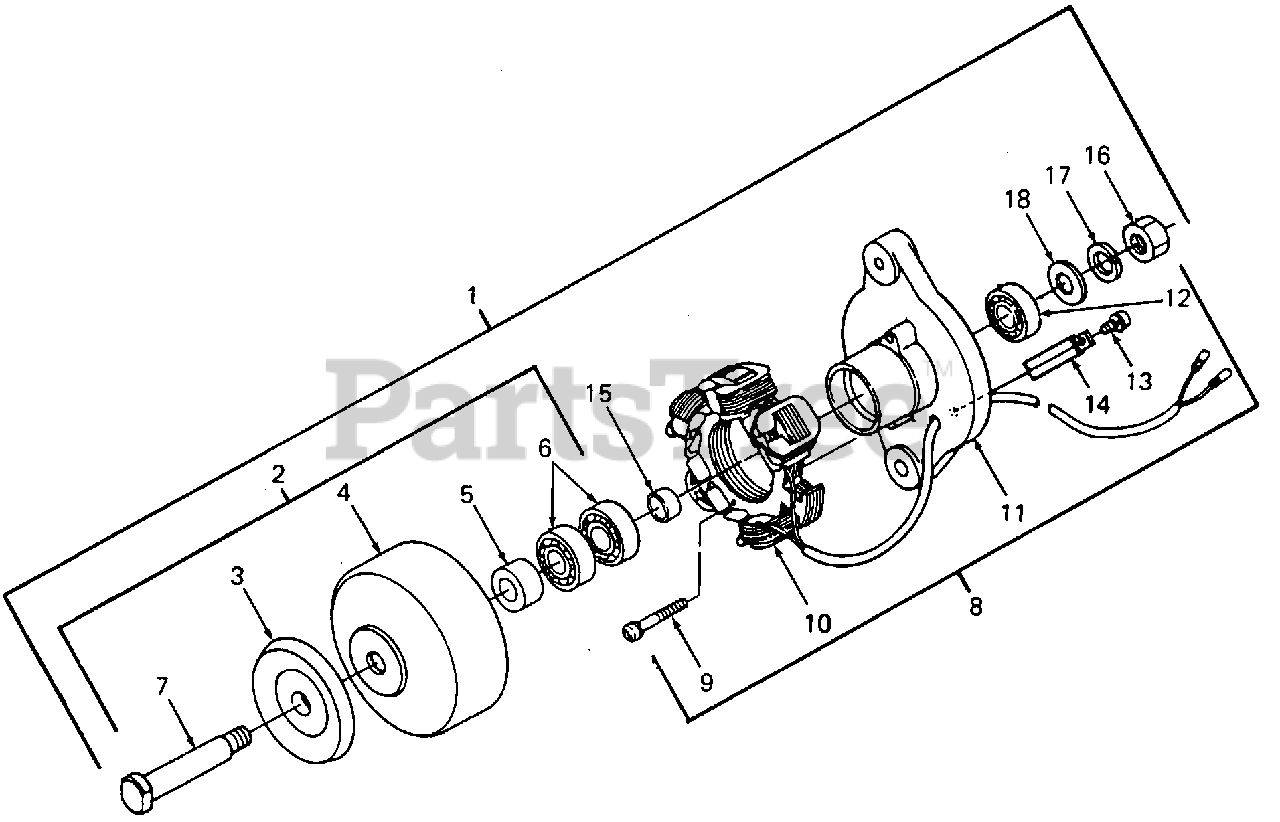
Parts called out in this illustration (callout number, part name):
1	Alternator Assy
6	Bearing, Ball
9	Screw, Round Head
12	Bearing, Ball
13	Screw, Round Head
17	Washer, Spring
18	Washer, Plain
